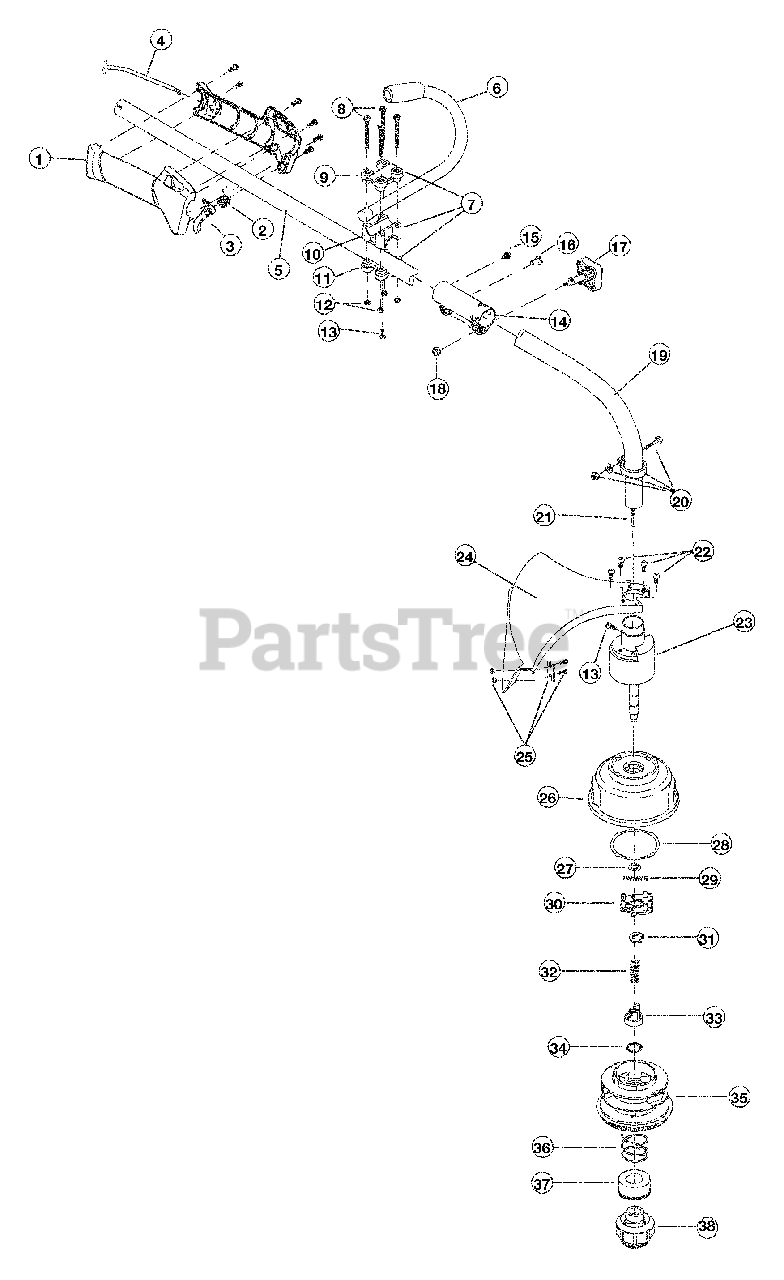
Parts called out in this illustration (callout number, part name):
1	Throttle Housing Assembly
2	Throttle Trigger Spring
3	Throttle Trigger
4	Throttle Cable Assembly
5	Upper Drive Shaft Housing Assembly
6	J-Handle Assembly
7	Handle Bracket Assembly
9	Upper Handle Clamp
10	Middle Handle Clamp
11	Lower Handle Clamp
13	Anti-Rotation Screw
14	Split Boom Coupler
17	Adjustment Knob
18	Knob Retaining Nut
19	Lower Drive Shaft Housing Assembly
20	Lower Clamp Assembly
21	Lower Flexible Drive Shaft
22	Shield Mounting Screw
23	Bushing Housing Assembly
24	Shield Assembly
25	Blade Assembly
26	Outer Spool Assembly
27	Retainer
28	Thrust Washer
29	Small Spring
30	Slider
33	Plunger
35	Inner Reel
36	Large Spring
37	Foam Seal
38	Bump Head Knob Assembly
